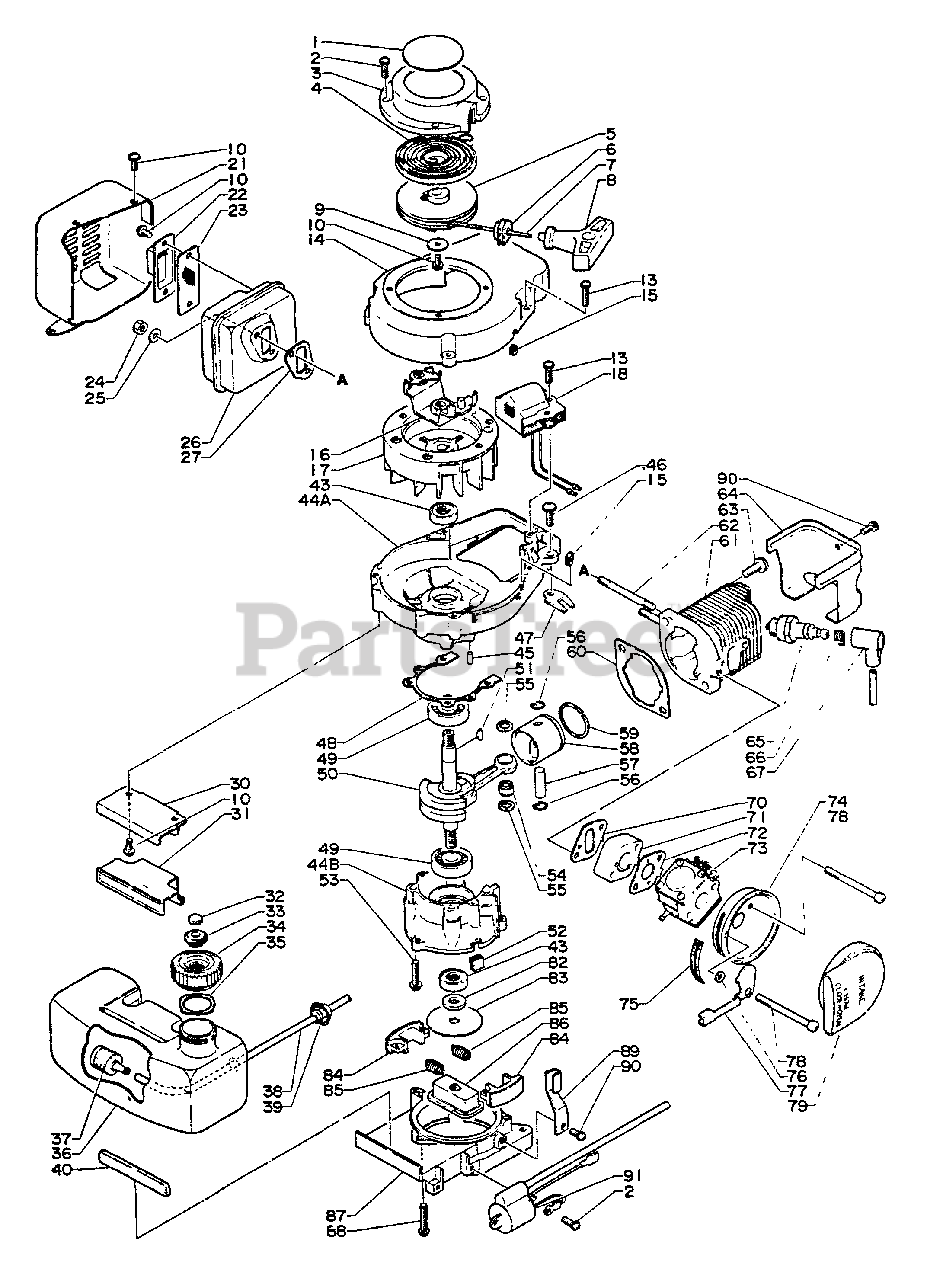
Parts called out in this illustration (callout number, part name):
1	LABEL - ECHO
2	SCREW - 4X12
3	CASE, STARTER
4	SPRING, REWIND
5	REEL, ROPE
6	GUIDE, ROPE
7	ROPE, STARTER - 3X850
8	GRIP, STARTER
10	SCREW - 4X10
13	SCREW - 4X20
14	CASE, FAN
16	STARTER PAWL ASSY
17	FLYWHEEL
18	COIL, IGNITION
21	COVER, EXHAUST
21	MUFFLER ASSY
22	GUIDE, EXHAUST
23	SCREEN, SPARK ARRESTOR
24	LOCKNUT - 5
25	WASHER - 5
26	MUFFLER
27	GASKET, EXHAUST
30	BRACKET, FUEL TANK
31	CUSHION
34	CAP
35	GASKET, CAP
36	TANK, FUEL
37	FILTER, FUEL
38	PIPE - 3X5X150 -- BLACK
40	CUSHION
43	SEAL, OIL
44	CRANKCASE KIT
45	PIN - LOCATING
46	SCREW - 5X14
47	BRACKET, THROTTLE CABLE
48	GASKET, CRANKCASE
49	BEARING, BALL - 6200
50	CRANKSHAFT ASSY
52	PLUG
53	SCREW - 5X30
54	BEARING, NEEDLE - 8
55	SPACER, PISTON
56	RING, RETAINING
57	PIN, PISTON
58	PISTON
59	RING, PISTON
60	GASKET, CYLINDER
61	CYLINDER
63	SCREW - 6X22
64	COVER, ENGINE
65	SPARK PLUG -- BM-6A
66	TERMINAL, SPARK PLUG CAP
67	CAP, SPARK PLUG
70	GASKET, INTAKE
71	INSULATOR, INTAKE
72	GASKET, INTAKE
73	CARBURETOR
74	CASE, AIR FILTER
76	WASHER - 5
77	SHUTTER, CHOKE
78	SCREW - 5X57
79	FILTER, AIR
83	PLATE, CLUTCH
84	SHOE, CLUTCH
85	SPRING, CLUTCH
86	HUB, CLUTCH
87	CASE, CLUTCH
88	SCREW - 4X25
89	HOLDER
90	SCREW - 5X10
91	COIL, IGNITION
